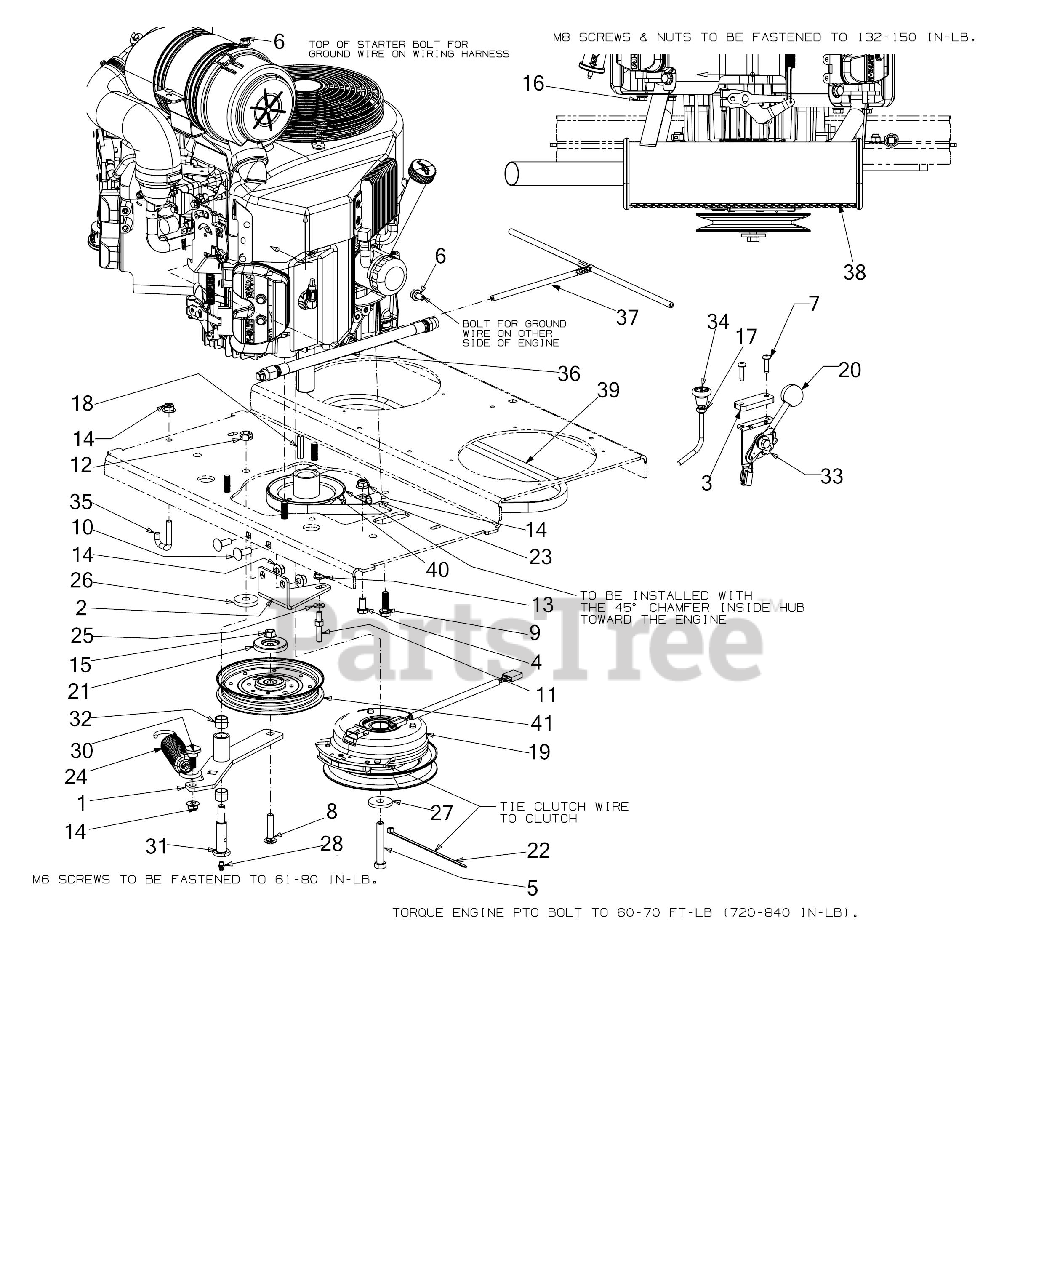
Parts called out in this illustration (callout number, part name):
1	TRANSMISSION IDLER BRACKET
2	RETAINER BRACKET
3	THROTTLE CABLE SPACER
4	HEX SCREW 3/8-16 x .75
5	SCREW 7/16-20:2.75 GR5
6	SCREW M8 x 1.25 x 16MM GR8.8
7	SCREW 1/4-20 x 1.0
8	CARRIAGE BOLT 3/8-16 x 1.75 GR5
9	SCREW 3/8-16 x 1.25 GR5
10	CARRIAGE BOLT 3/8-16 x 1.00 GR5
13	FLANGE LOCK NUT 5/16-18
15	HEX LOCK NUT
16	HEX FLANGE NUT
17	HEX JAM NUT 3/8X24
18	SQUARE KEY 1/4 x 1.50
19	ELECTRIC PTO CLUTCH
21	PULLEY CAP
22	7" CABLE TIE
23	J TYPE CLIP
24	EXTENSION SPRING W/HOOK
25	FLAT WASHER
26	FLAT WASHER 47 x 1.50 x .225
27	FLAT WASHER .45 x 1.5 x .172 HT
28	GREASE FITTING
30	SHOULDER SCREW .625 x .302 x 3/8-16
31	SHOULDER BOLT 7/16-14
32	SLEEVE BEARING
33	THROTTLE CABLE 59"
34	CHOKE CABLE
35	ROD SPRING HOOK
36	OIL DRAIN HOSE
37	ROLLOVER VENT HOSE ASSEMBLY
38	KAWASAKI MUFFLER
39	TRANSMISSION BELT 61.5
40	PULLEY - PUMP DRIVE
41	IDLER PULLEY
